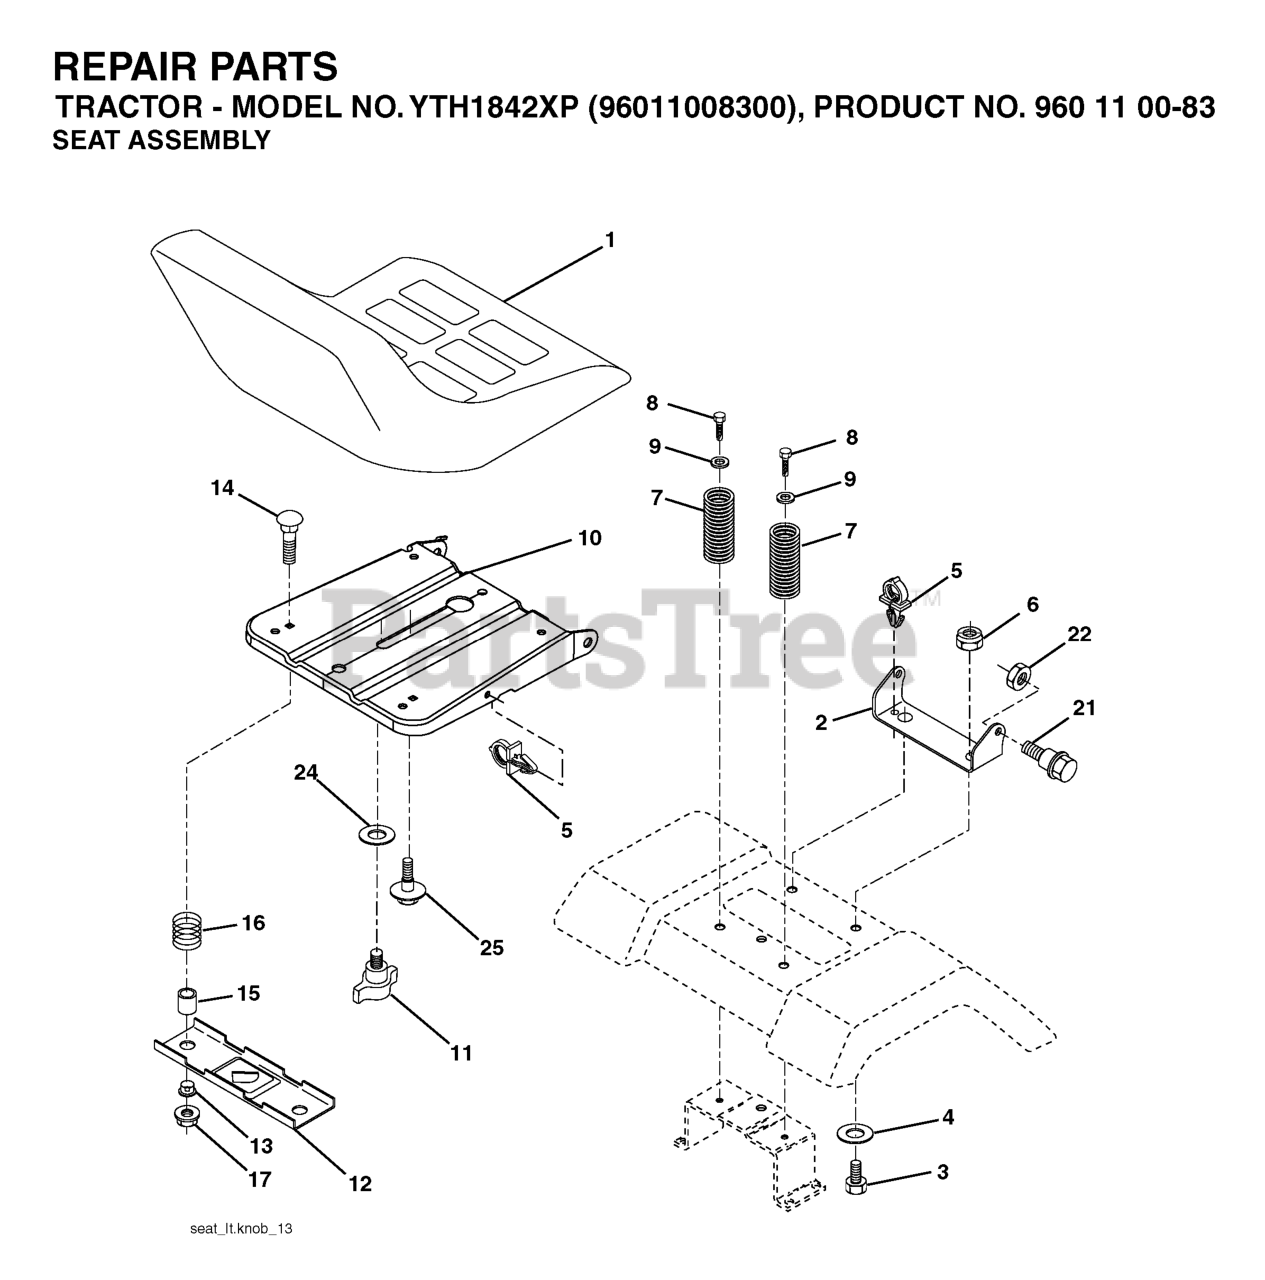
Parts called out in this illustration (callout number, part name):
1	SEAT
2	SEAT PIVOT BRKT
3	BOLT, HEX 3/8-16X1
6	NUT
7	SPRING COMPRESSION
8	SCREW 3/8-16X1
9	WASHER
10	PAN SEAT
11	KNOB.SEAT.ADJ.WINGNUT
12	BRKT.MNTNG.SWITCH.SEAT.BLACK
14	BOLT.ROUND.HEAD.SQUARE.NECK
15	SPACER SPLIT
16	SPRING COMPRESSED
17	NUT T
21	BOLT.SHOULDER.5/16-18
22	NUT.71038.31-18.HEX.NYLOCK
25	BOLT,SHOULD
